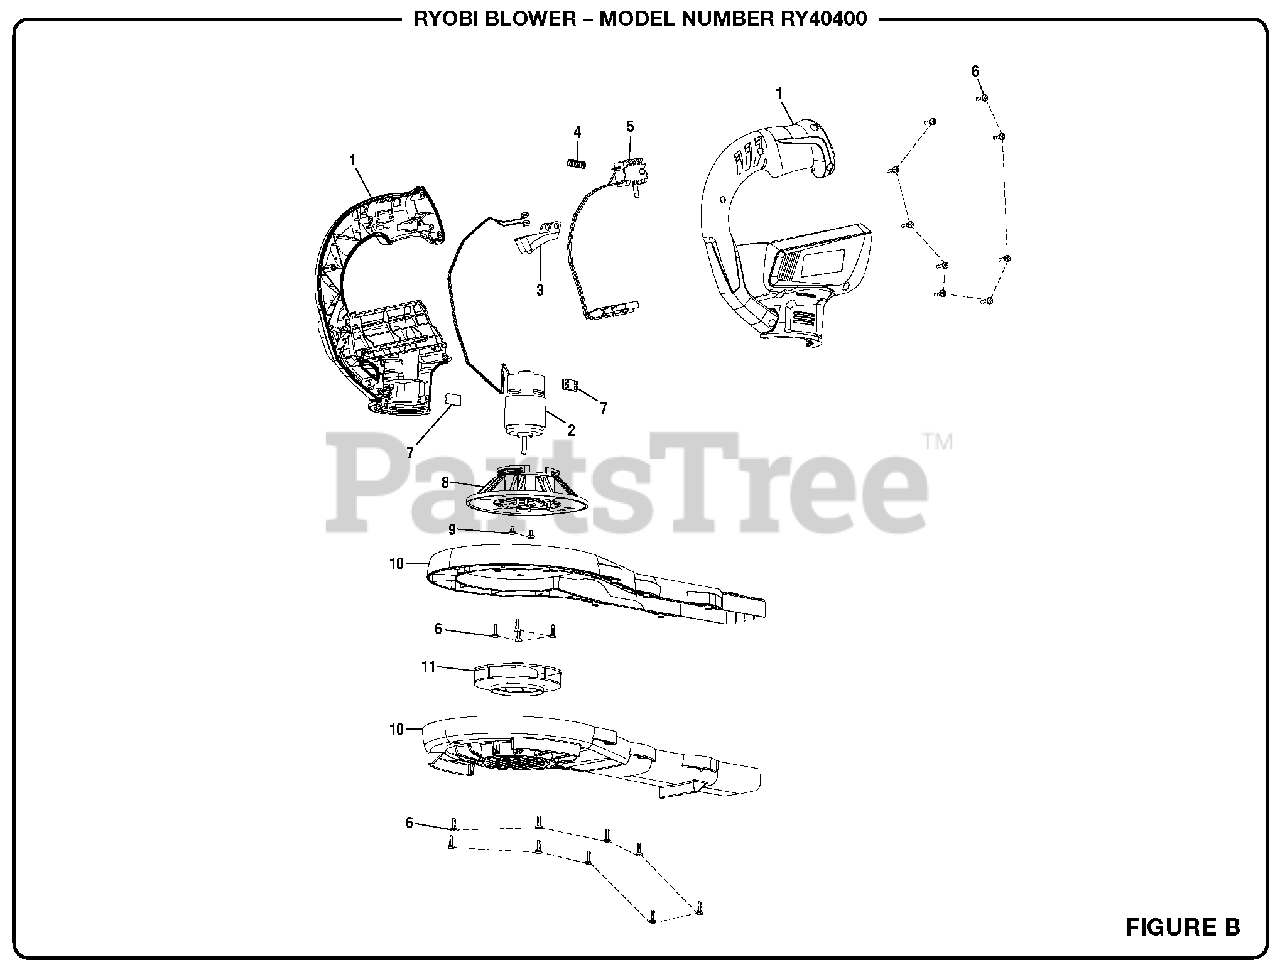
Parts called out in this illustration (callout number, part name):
1	Handle Assembly
2	Motor Assembly
3	Switch Trigger
4	Compression Spring
5	Switch Assembly
6	Screw (M4 x 14 mm)
8	Motor Mount
9	Screw w/Washer (M4 x 10 mm)
10	Blower Housing Assembly
